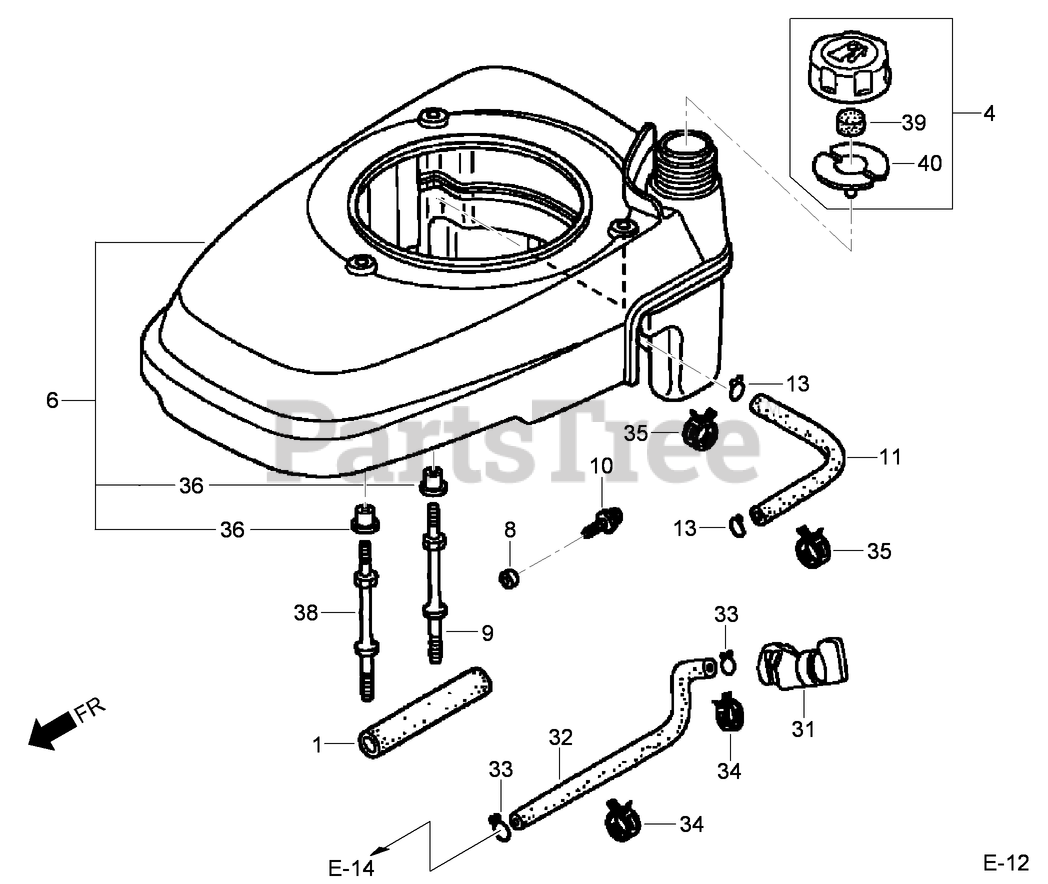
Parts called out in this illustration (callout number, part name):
1	SUPPORTER-RUBBER (107 mm)
4	FUEL TANK CAP ASM
6	COVER-FAN, N H1 (BLACK)
8	COLLAR-TURN SIGNAL, FRONT
9	BOLT-STUD (H=42.5MM)
10	SCREW-WASHER (5X10)
11	TUBE-FUEL (5.3X150) (FKM) (engine serial numbers starting at 3698327)
11	HOSE-FUEL, BULK (5.5X3000) (5.5X100) (engine serial numbers up to 3698326)
13	CLIP-TUBE (B10)
31	PETCOCK ASM (engine serial numbers up to 6901760)
32	TUBE-FUEL (engine serial numbers starting at 6901760)
32	TUBE-FUEL (FKM) (engine serial numbers starting at 3698327)
33	CLIP-TUBE (B8)
34	CLAMP-TUBE (D8) (engine serial numbers starting at 3698327)
35	CLAMP-TUBE (D10) (engine serial numbers starting at 3698327)
36	COLLAR-COVER, FAN
38	BOLT-STUD (H=42.5MM)
39	SPONGE-BREATHER, FUEL CAP
40	GASKET-CAP, FUEL
